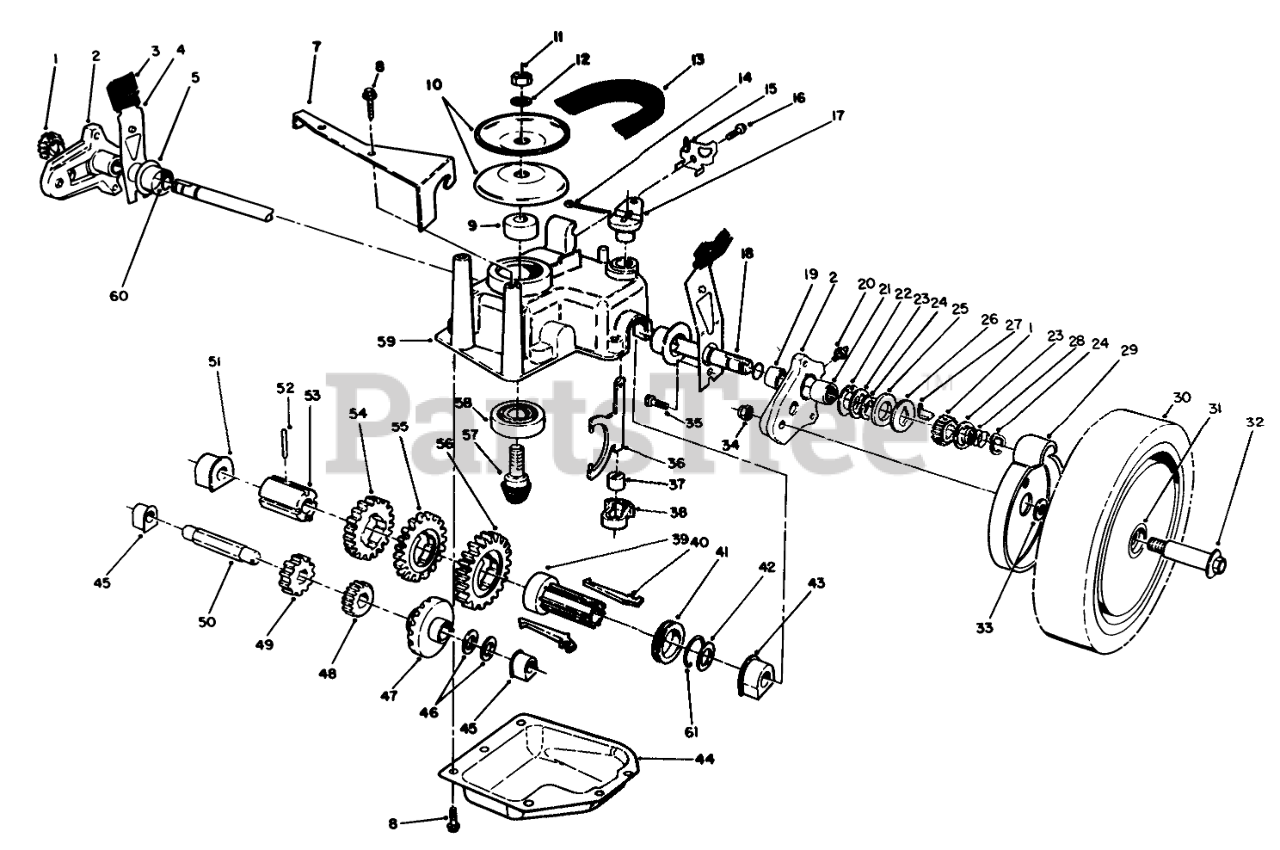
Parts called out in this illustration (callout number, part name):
1	GEAR-PINION
2	Pivot Arm Assembly (Incl. Ref #19, 20, & 21)
3	KNOB-ARM
4	SPRING ARM ASM SP
5	CAP-END
7	Bracket-Guide
8	SCREW-HWHTF
9	SPACER
10	Pulley Half
11	NUT-HEX
12	WASHER-FLAT
13	V-BELT E
14	PIN-COTTER
15	CLAMP-CABLE
16	SCREW-HWHTF
17	LEVER-SHIFT
18	SHAFT-OUTPUT
19	BUSHING
20	FITTING-GREASE
21	BEARING-ROLLER
22	WASHER-ARM, PIVOT
23	WASHER-THRUST, KEYED
24	RING-CLIP, LOCKING
25	RING-FRICTION
26	WASHER-CLUTCH
27	KEY-ROCKING, LH
28	SPRING-COMPRESSION
29	COVER-WHEEL
30	Wheel-Tire & Gear Ass-y (Incl. Ref. #31)
31	BUSHING
32	WHEEL BOLT
33	SPACER-COVER, WHEEL
34	Nut
35	SCREW-HWH
36	YOKE-SHIFT
37	BUSHING-YOKE
38	RETAINER-FORK, SHIFT
39	SLEEVE-KEY, SHIFT
40	KEY-SHIFT
41	COLLAR-SHIFT
42	WASHER-PLAIN
43	BUSHING-OUTPUT
44	Cover-Gearcase
45	BUSHING
46	WASHER-THRUST
47	Gear-Bevel
48	PINION-20T
49	PINION-25T
50	SHAFT-INTERMEDIATE
51	BUSHING
52	PIN-ROLL
53	SLEEVE-GEAR
54	GEAR-39T
55	GEAR-44T
56	GEAR-49T
57	Gear-Pinion
58	BEARING-BALL
59	CASE-GEAR, UPPER
60	O-RING
61	CLIP-SPRING
